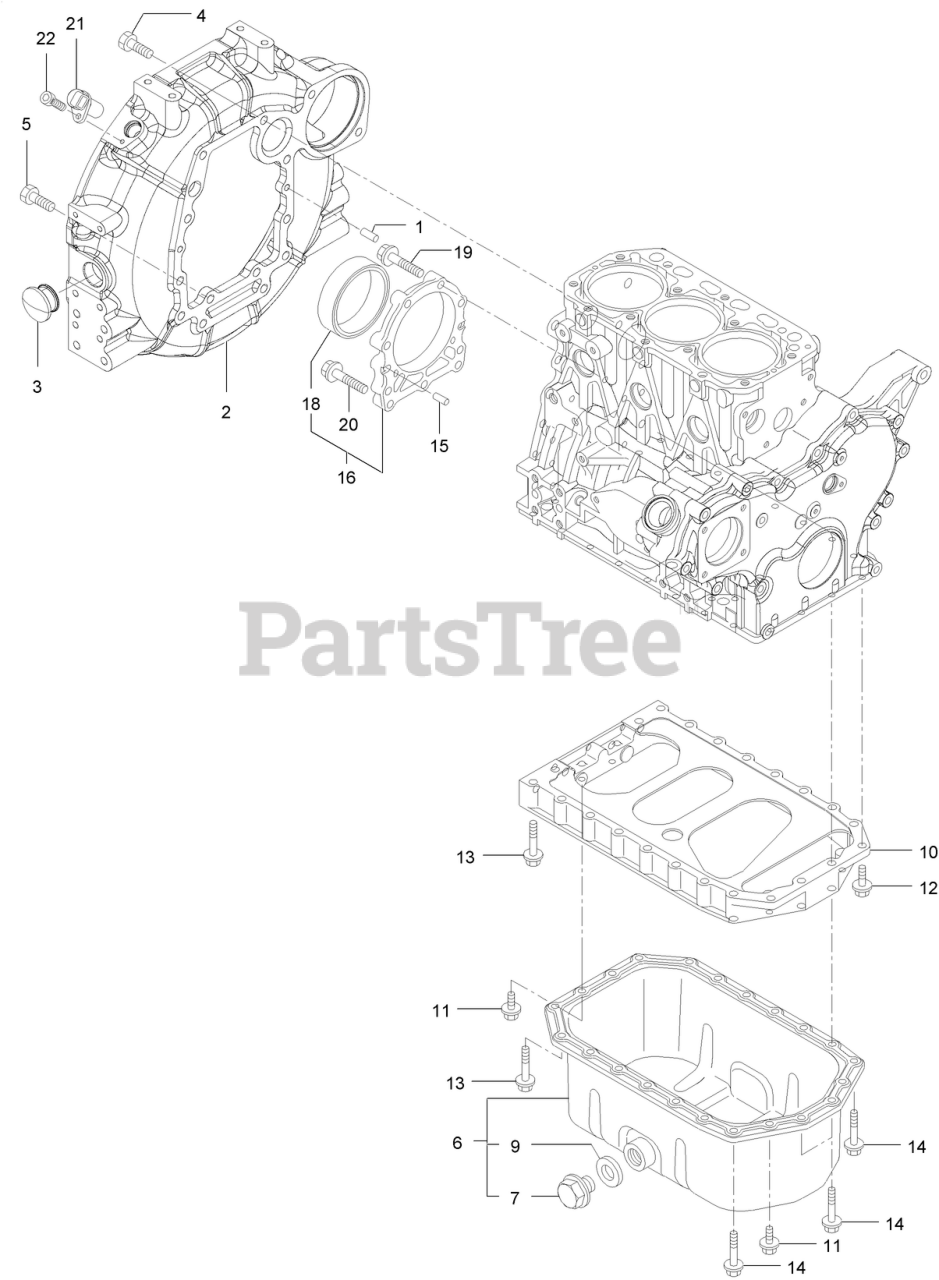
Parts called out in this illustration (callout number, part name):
2	HOUSING-FLYWHEEL
6	OIL PAN ASM
7	PLUG-DRAIN
9	WASHER-SEAL
10	SPACER, OIL PAN
16	OIL SEAL CASE ASM
18	SEAL-OIL
21	SENSOR-REV, FLYWHEEL
